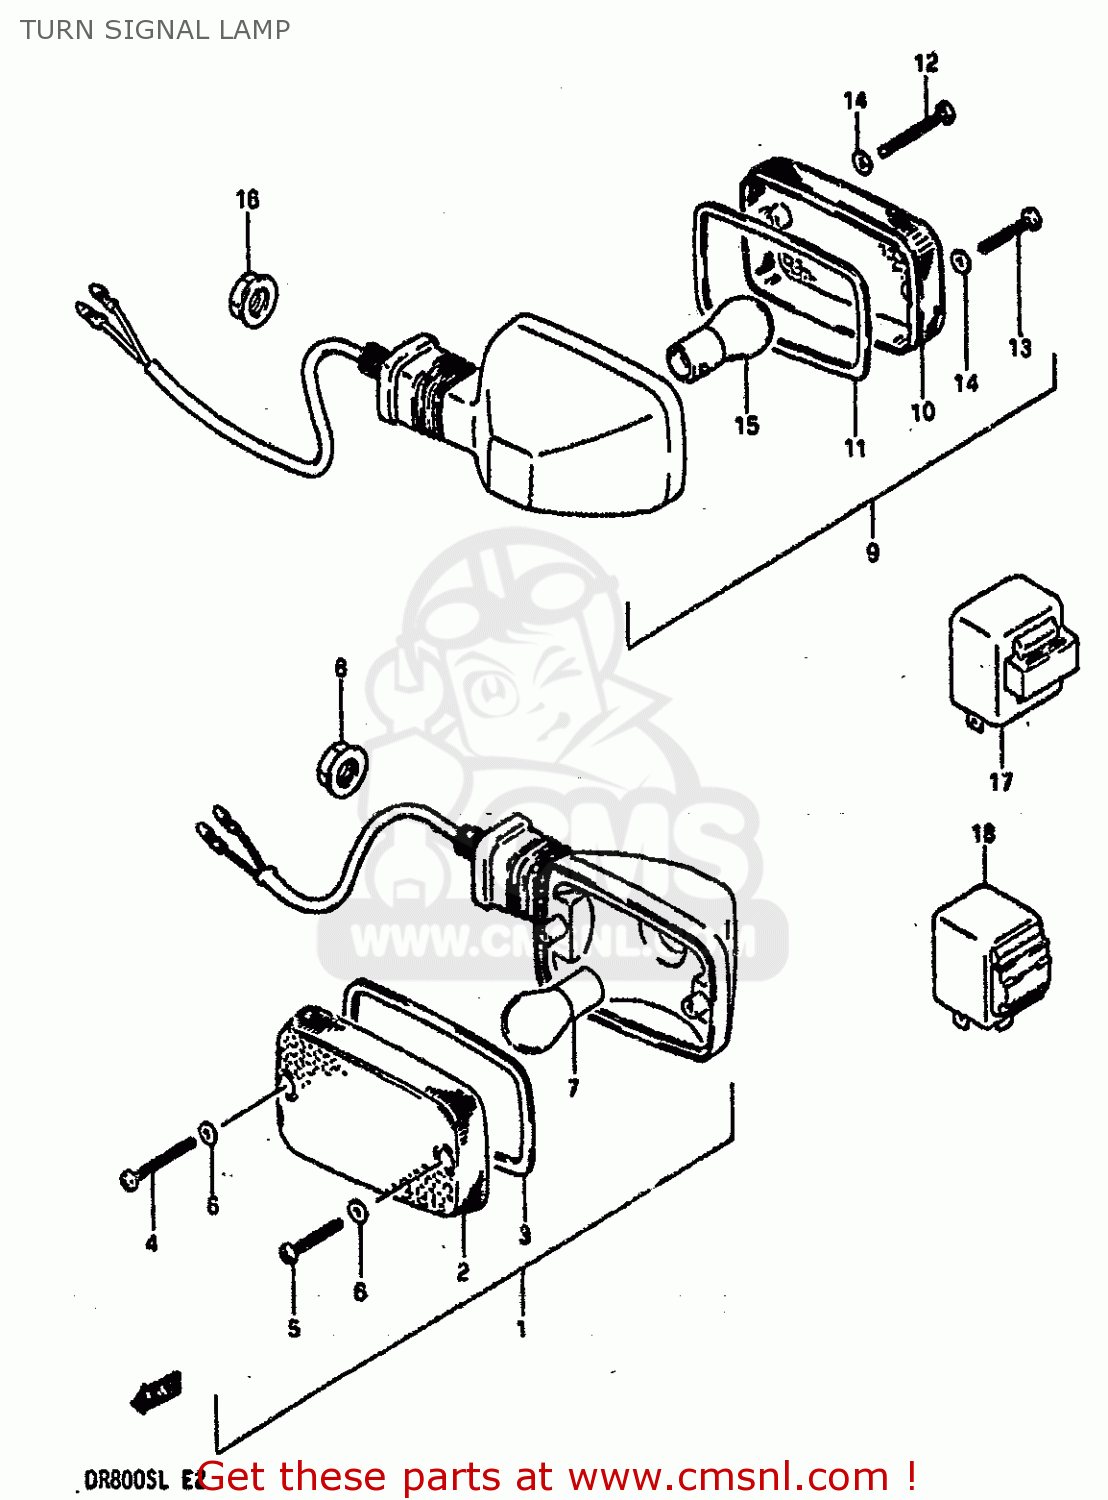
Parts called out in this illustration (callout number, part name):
1	LAMP ASSY,FR
2	LENS,FR
3	GASKET (NAS)
4	SCREW,TURN SIG LENS FITTING
5	SCREW
6	GASKET (NAS)
7	BULB(12V21W)
8	NUT
9	LAMP,RR TURNSI
10	LENS,RR
11	GASKET (NAS)
12	SCREW,TURN SIG LENS FITTING
13	SCREW
14	GASKET (NAS)
15	BULB(12V21W)
16	NUT
17	RELAY ASSEMBLY,TURN SIGNAL
18	RELAY ASSY,TUR
